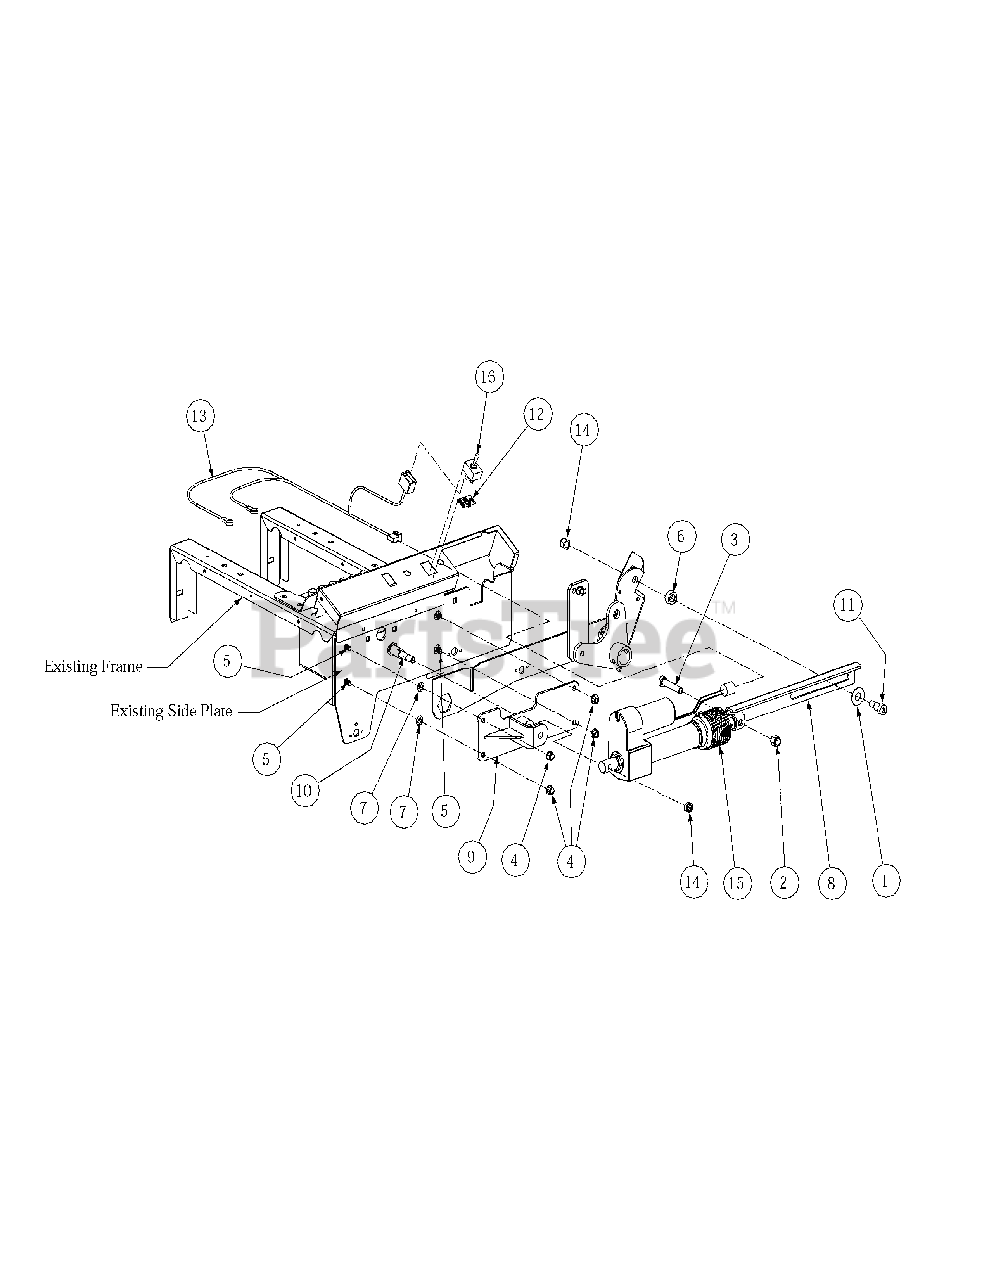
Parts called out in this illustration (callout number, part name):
1	Washer, 1-1/2 x 5/8 x .05
2	Nut, 1/2-13, Nylon Insert
3	Hex Head Cap Screw, 1/2-13 x 2-1/2
4	Nut, 3/8-16, Hex Flange Lock
5	Carriage Bolt, 3/8-16 x 1
6	Spacer, .630 ID x 1.06 OD x .440
7	Push Retainer, 3/8
8	Arm Lift Deck Weldment
9	Actuator Mounting Plate
10	Pin, Deck Pivot Lift
11	Shoulder Screw, 0.625 x .750
12	Label, Deck Lift Up/Down
13	Harness Assembly
14	Jam Nut, 1/2-13
15	Actuator
16	Toggle Switch, On-Off-On
